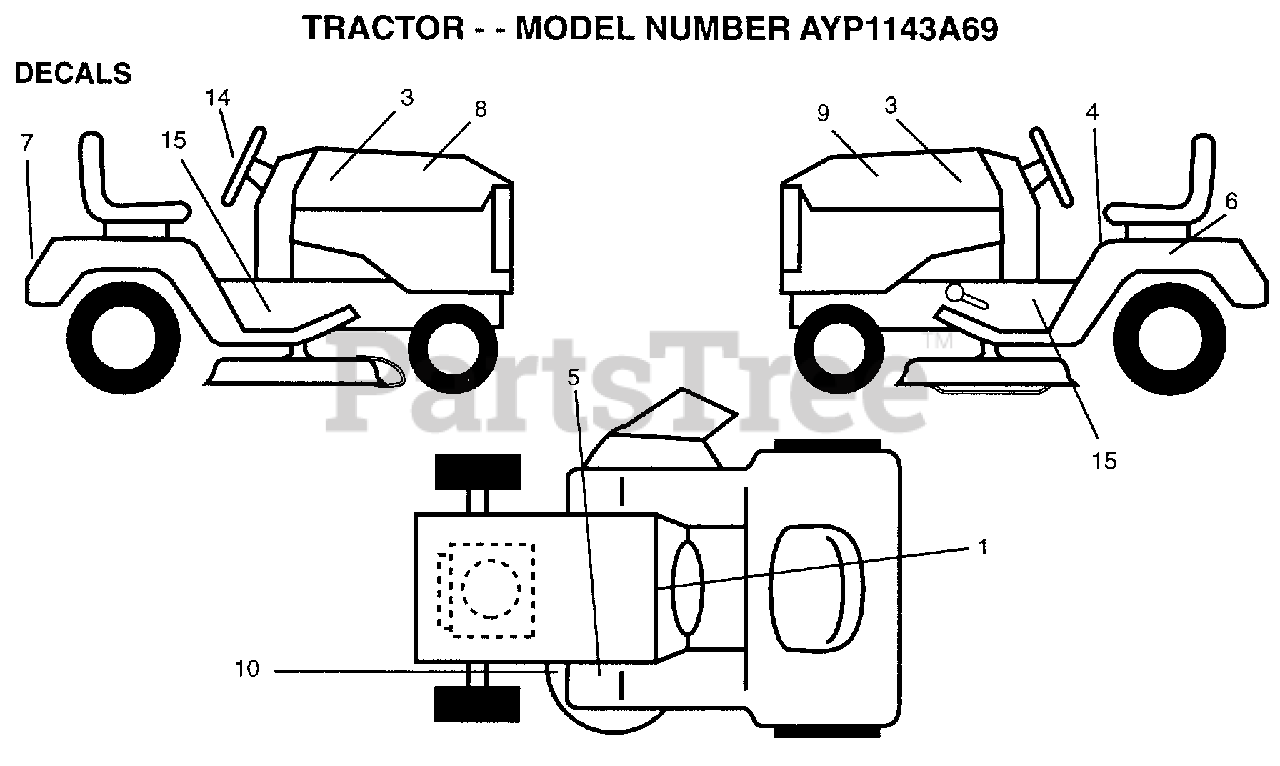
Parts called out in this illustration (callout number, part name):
3	DECAL.INS.HD.14.5
4	DECAL
6	DECAL.BTRY.DANGER
8	DECAL.HD.RH.WIZAR
9	DECAL.HD.LH.WIZAR
10	DECAL
14	DECAL.INS.STRG.WL
15	DECAL CHASSIS WIZ
